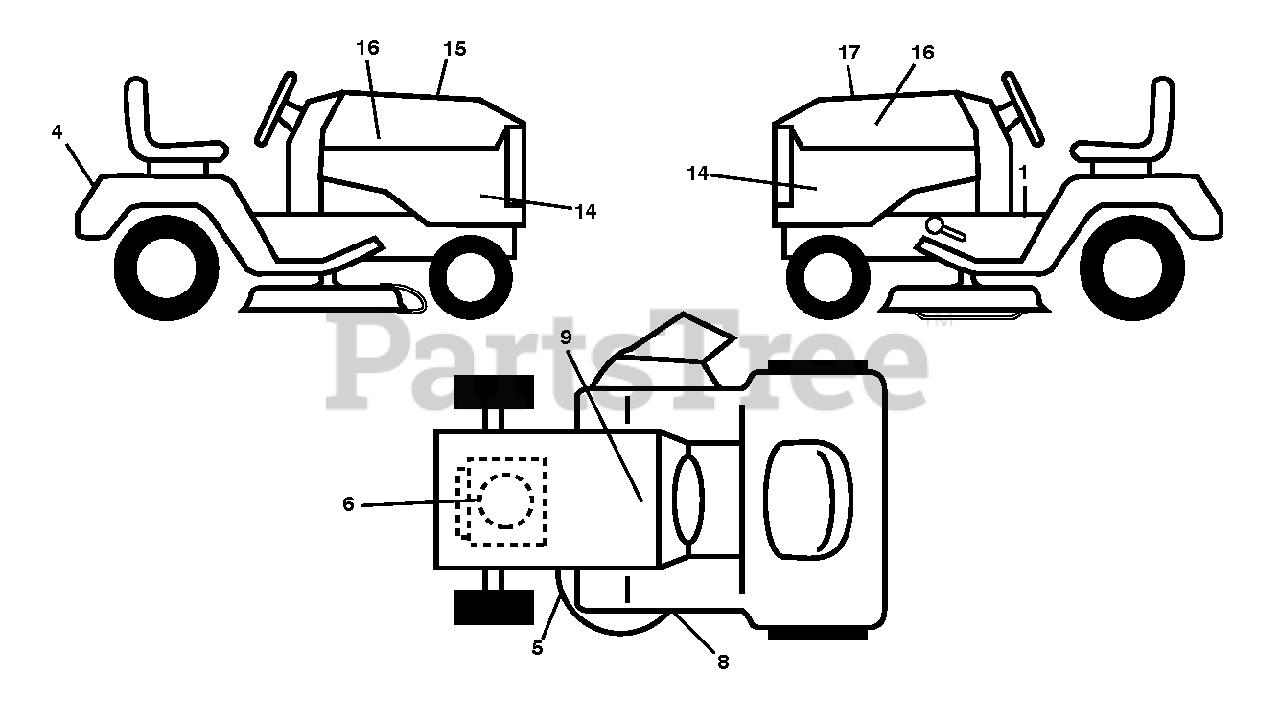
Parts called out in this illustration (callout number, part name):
1	DECAL.WARN.START.INSTRUCTIONS
4	DECAL.FENDER
5	DECAL.MOWER
6	DECAL.ENG.BS.23HP.XRD
8	DECAL.MOWER.SCH.48/54
9	DECAL BTRY SYMBOLS
14	Decal, Side Panel HUSGT2 YTH2348 Husqvarna
15	DECAL.WARNING.CUST.RESP.E85.
16	RP.DECAL.BADGE.170MM.TEXTLOGO
17	DECAL.RPL.BSM44.INTK.TLW.48.K4
